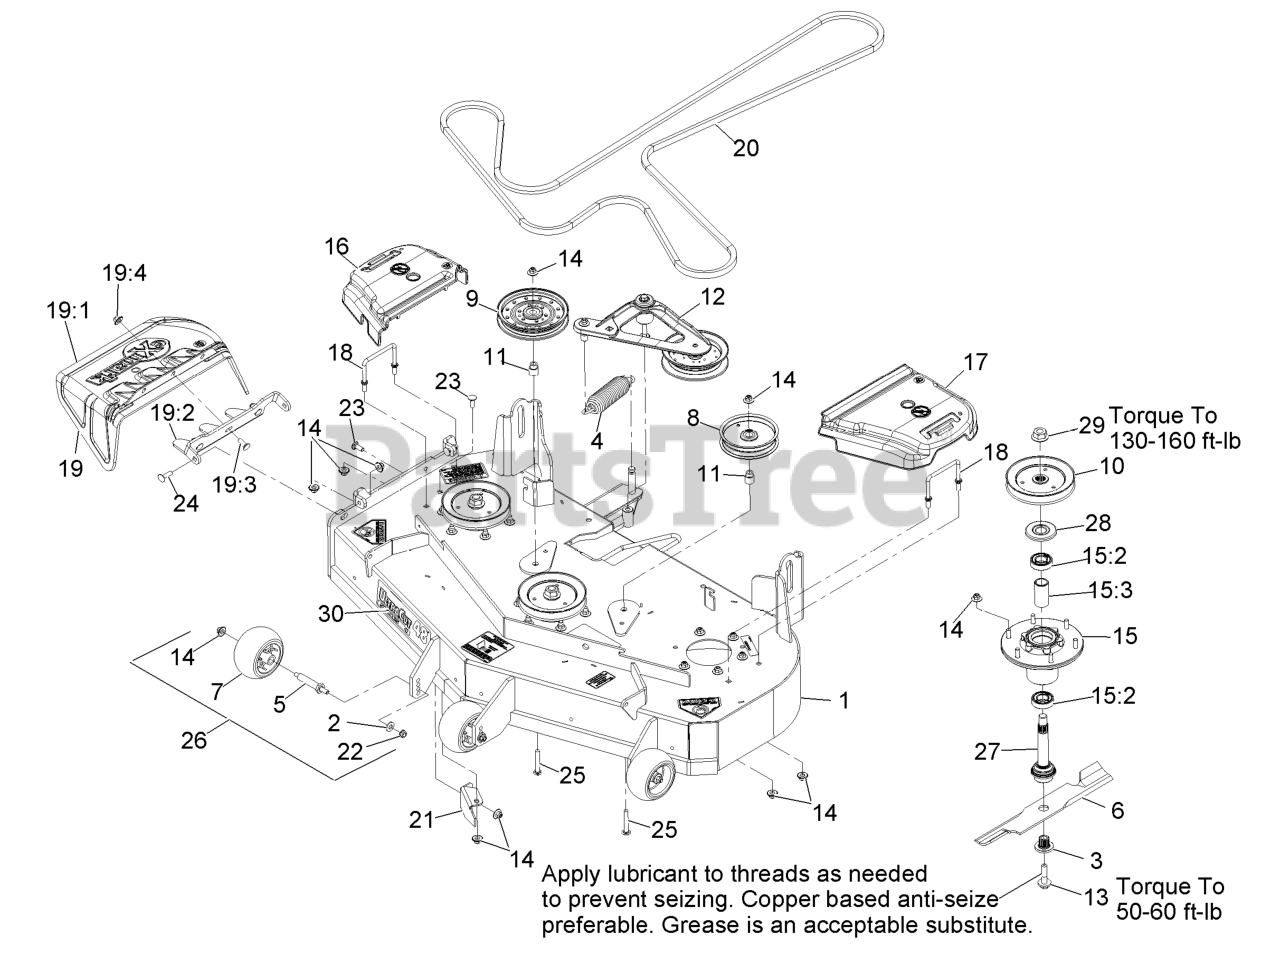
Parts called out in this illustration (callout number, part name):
2	WASHER-BELLEVILLE
3	BUSHING,SPLINED
7	ROLLER-SCALP, ANTI
8	PULLEY-IDLER
10	SHEAVE,BLADE DRIVE 5.90
11	BUSHING-IDLER
12	DECK IDLER ASM
13	SCREW,SEMS 1/2-20 X 2.19
14	Nut-Nyloc 3/8-16 Flg
15	ASM-CUTTER HSG WITH BEARINGS
15:2	BEARING-BALL
15:3	SPACER-BEARING
16	COVER-BELT, RH
17	COVER-BELT, LH
18	WIREFORM-COVER
19	ASM,DISCHARGE CHUTE
19:1	CHUTE,DISCHARGE
19:2	BRACKET,DISCHARGE CHUTE
19:3	SCREW-CARR
19:4	Nut-Nyloc 3/8-16 Flg
21	BAFFLE,DISCHARGE
22	NUT-HHF, WHIZ
23	SCREW-CARR
24	Bolt-Carriage 3/8-16 X 1 1/4
25	SCREW-CARR
27	ASM-SPINDLE AND SEAL
28	GUARD,BEARING TOP .989
29	NUT-FLANGE
30	DECAL,ULTRACUT 48 SERIES
